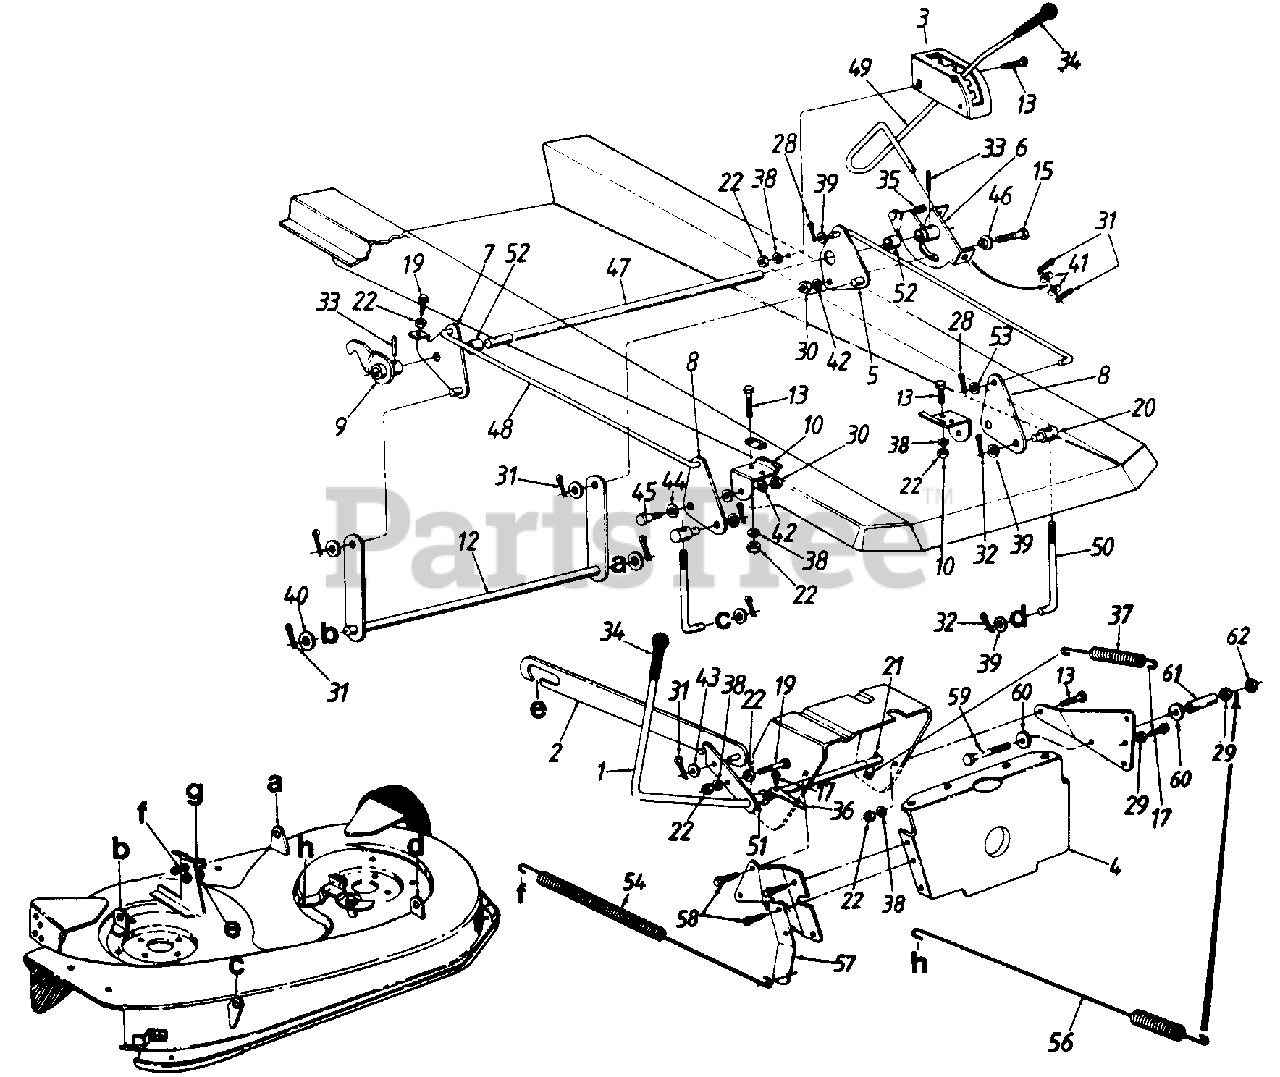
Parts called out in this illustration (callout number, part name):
1	Blade Engagement Lever Ass'y.
5	Deck Lift Brkt. Ass'y.
6	Deck Lift Handle Retainer Ass'y.
7	Deck Lift Brkt. Ass'y.
8	Deck Lift Bracket
9	Deck Lift Float Brkt Ass'y.
10	Deck Lift Pivot Brkt.
12	Stabilizer Shaft Ass'y.
13	Hex Bolt 5/16-18 x .75" Lg.
15	Hex Bolt 3/8-16 x 1" Lg.
17	Hex Wash. Hd. Scr. 1/4-20 x 1.5" Lg
19	Hex Wash.-Tap Scr. 5/16-18 x 1.25" Lg.
20	Ferrule
21	Clevis Pin
22	Hex Nut 5/16-18 Thd.
28	Cotter Pin 3/32" Dia.
29	Hex Nut 1/4-20 Thd.
30	Hex Nut 3/8-16 Thd.
31	Internal Cot. Pin 1/2" Dia.
32	Int. Cot. Pins 3/8" Dia.
33	Spring Pin Spir. 1/4" Dia.
35	Compression Spring 1.04"
36	Switch Actuator
37	Ext. Spring 5.86" Lg.
38	L-Wash 5/16" I.D.
39	Fl-Wash. .385 I.D. x .62
40	Fl-Wash. .635 I.D. x 1.12
41	Fl-Wash. .531 I.D. x .930
42	L-Wash. 3/8" I.D.
43	Fl-Wash. .385 I.D. x .87 O.D.
44	Spring Washer .530 I.D.
45	Shld. Bolt 500" Dia. x .215"
46	Shld. Spacer .625" I.D.
47	Rear Hgt. Adj. Shaft
50	J-Bolt 5.4" Lg.
51	Spacer. 511 I.D.
52	Spacer .885 I.D.
53	Fl-Wash. 5/16" I.D.
54	Ext. Spring 22.05" Lg.
56	Ext. Spring 15.38" Lg.
57	Spring Anchor
58	Hex Wash. Hd. AB-Tap Scr. 1/4 x .62" Lg.
59	Hex Bolt 1/4-20 x 2.6" Lg.
60	Fl-Wash. 25" I.D. x.93" O.D.
61	Spacer.255" I.D.
62	Hex L-Nut 1/4-20 Thd.
